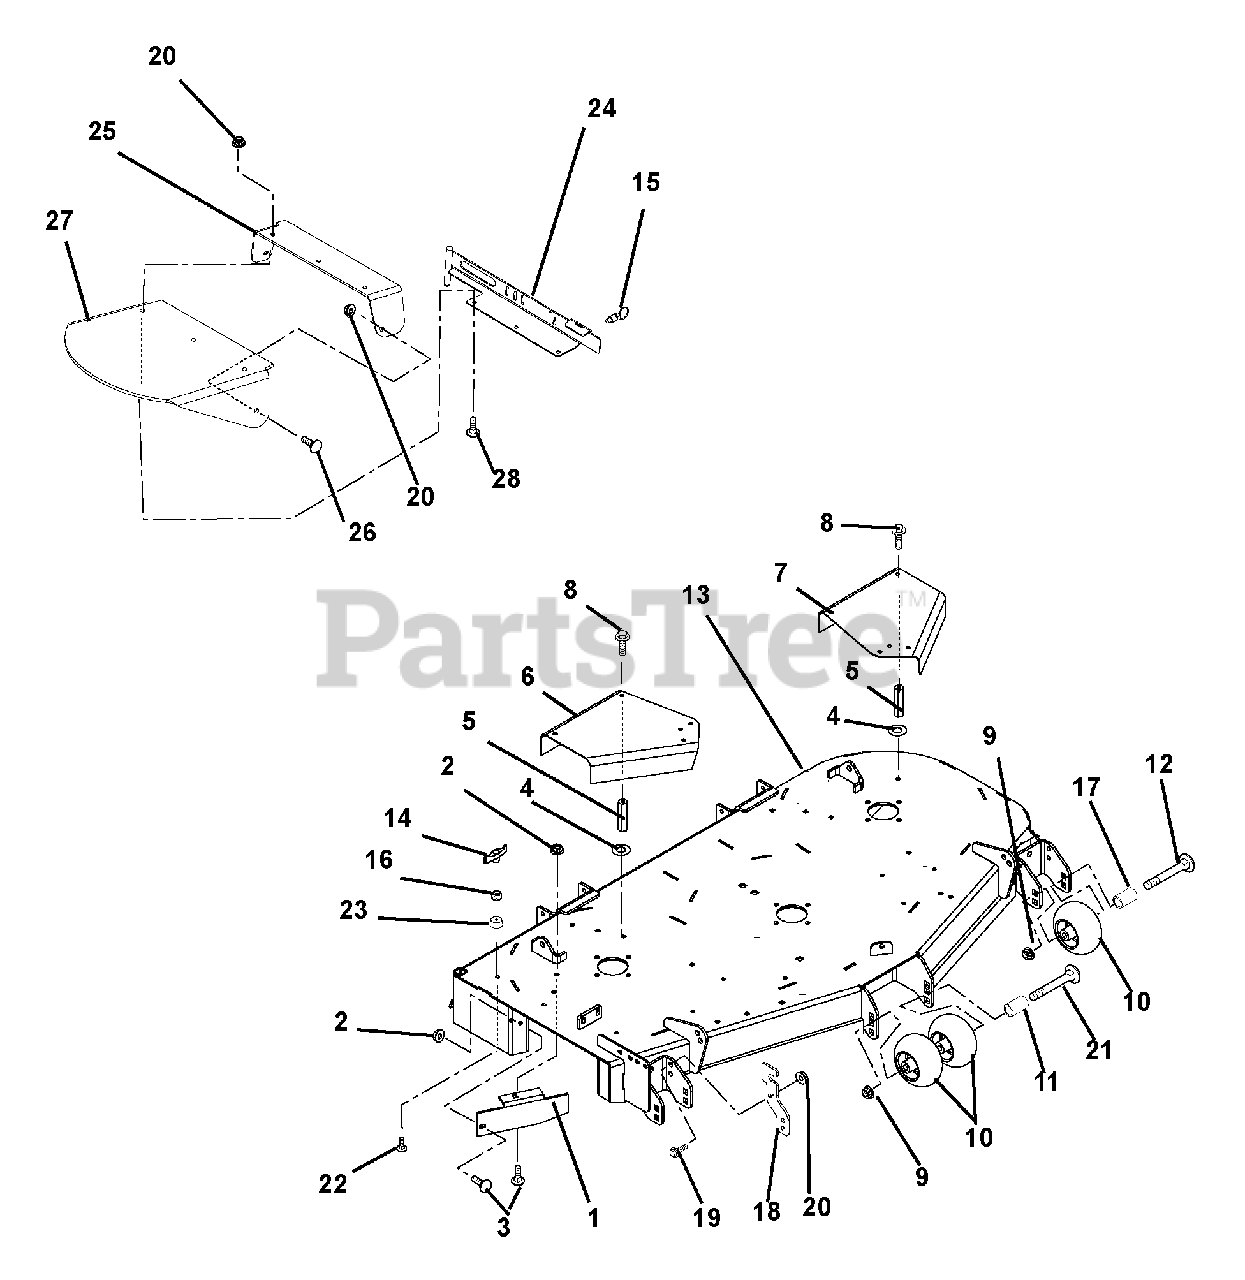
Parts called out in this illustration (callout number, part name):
1	60-in. Discharge Baffle (992156)
1	72-in. Discharge Baffle (992158)
2	Nut, .31-18 Nyloc Flange
3	Bolt, Round Head Square Neck .31-18 x 1.00 Grade 5
4	Washer, Lock Internal .375
5	Standoff, .38-16 x .50 Self Tapping
6	60-in. Right Hand Spindle Guard (992156)
6	72-in. Right Hand Spindle Guard (992158)
7	60-in. Left Hand Spindle Guard (992156)
7	72-in. Left Hand Spindle Guard (992158)
8	Bolt, SEMS .31-18 x .62
9	Nut .50-13 Nyloc Flange
10	Anti-Scalp Wheel
12	Bolt-Round Head Square Neck .50-13 x 5.00
13	60-in. Mower Deck (992156)
13	72-in. Mower Deck (992158)
14	Knob, Wing .312-18
15	Pin, Pull Plunger .50-13 Thread x .310
16	Nut, Locking Center .31-18
17	Spacer, .510 x .625 x 3.35
18	Chute, Storage Bracket
19	Bolt, Hex .38-16 x 1.00
20	Nut, .38-16 Nyloc Flange
21	Bolt, Round Head Square Neck .50-13 x 8.50
22	Bolt, Round Head Square Neck .31-18 x 1.50
23	Bumper, Recessed 1.50 x .63 , .31 Thru Hole
24	60-inch Discarch Chute Mounting Weldment (992156)
24	72-inch Discharge Chute Mounting Weldment (992158)
25	Rubber Discharge Chute Support
26	Bolt, Round Head Square Neck .38-16 x 1.00 Grade 5
27	Chute, Rubber Discharge
28	Bolt, Round Head Square Neck .38-16 x 1.25 Grade 5
